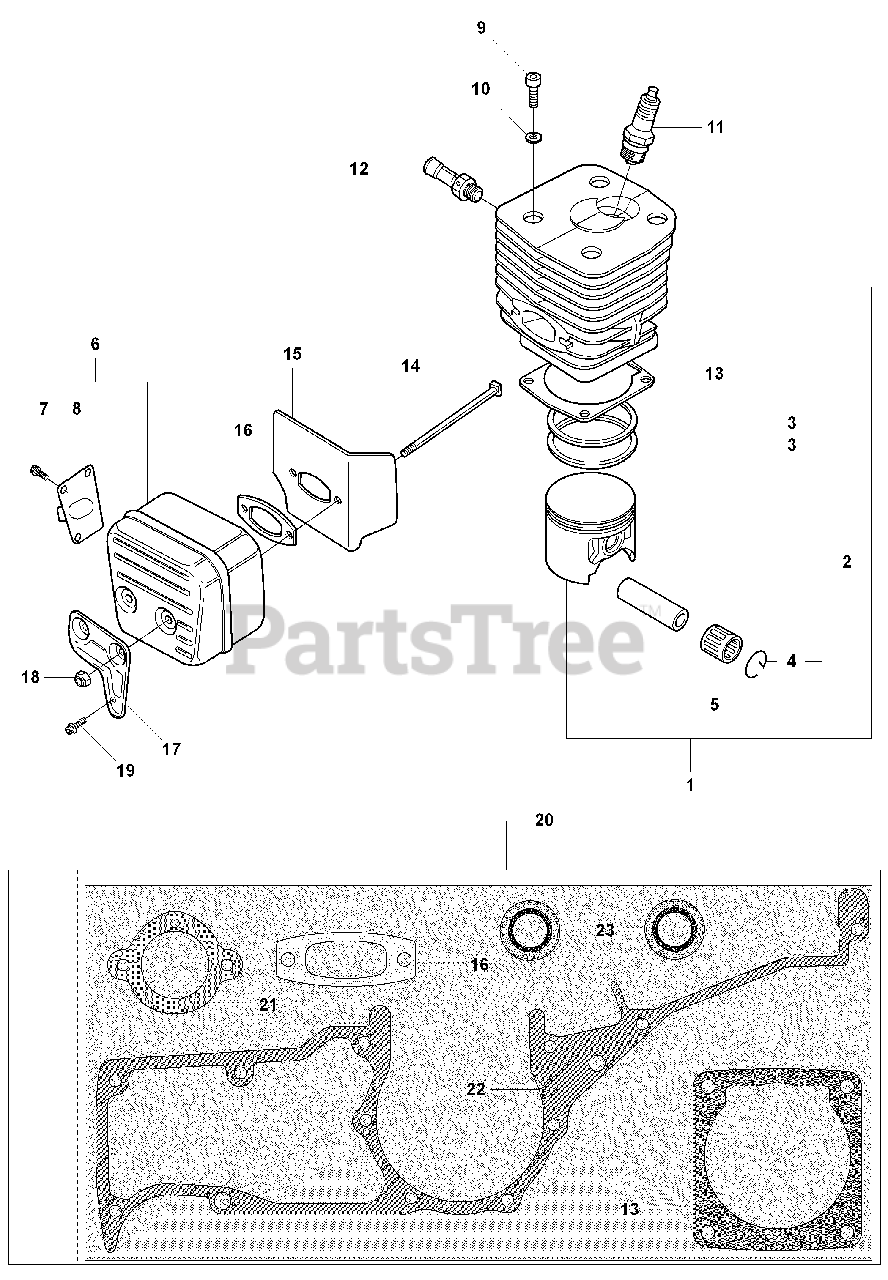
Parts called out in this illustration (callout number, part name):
1	CYLINDER
2	PISTON CPL
3	PISTON RING
5	SUPPORT BUSHING
6	MUFFLER
8	EXHAUST DUCT
10	WASHER STEEL
11	SPARK PLUG
12	DECOMPRESSION VALVE
13	GASKET
15	COOLING PLATE
16	GASKET MUFFLER
17	MUFFLER SUPPORT
20	GASKET KIT
21	GASKET
22	CRANKCASE GASKET
23	SEALING RING
